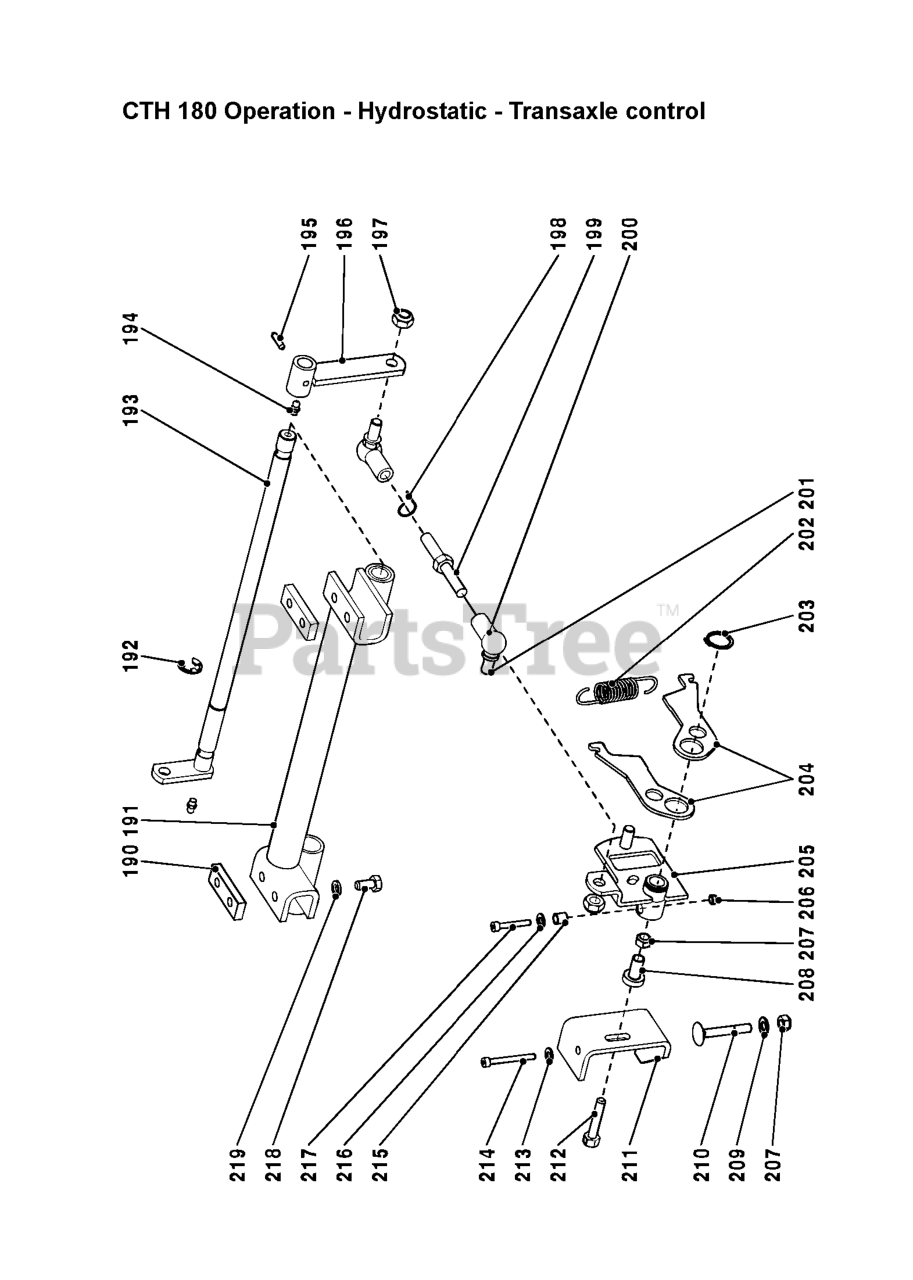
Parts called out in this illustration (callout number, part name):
192	RETAINING RING
200	BALL JOINT
201	BALL JOINT
203	RETAINING RING
207	NUT
219	SPRING WASHER
